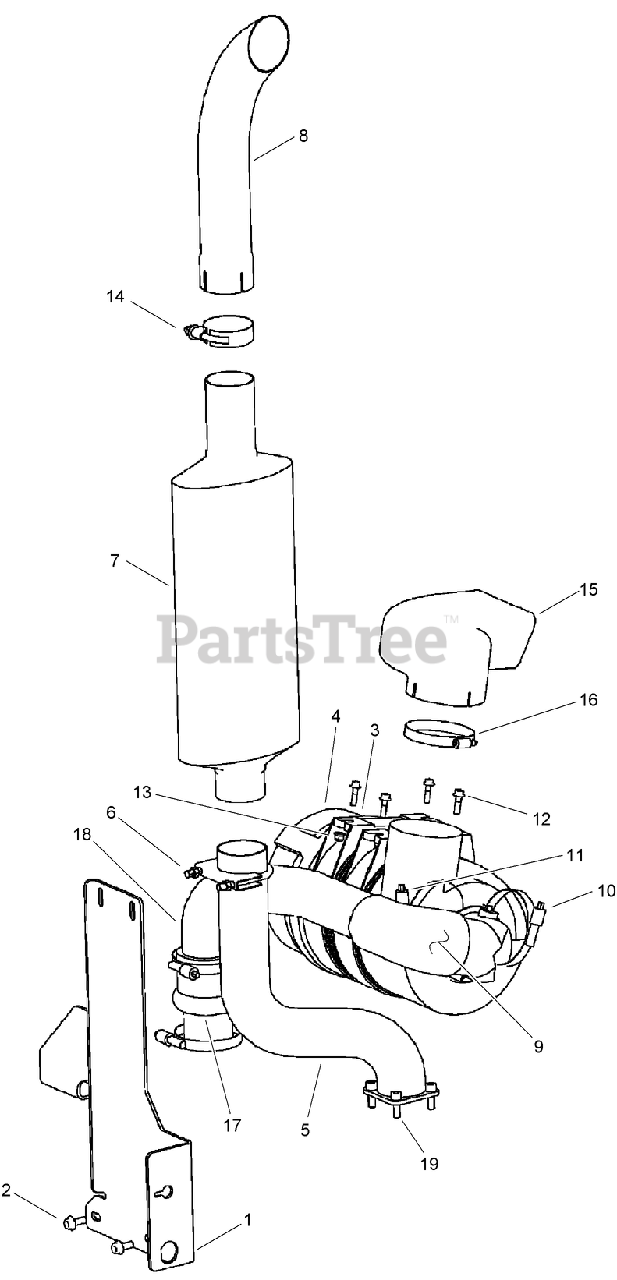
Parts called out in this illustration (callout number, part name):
1	SUPPORT-Muffler Mount
2	SCREW-FLANGE
3	MOUNT-Air Cleaner
4	ASM-Air Cleaner
5	TUBE-EXHAUST
6	BOLT-U, CLAMP
7	MUFFLER-VERTICAL, OVAL
8	EXHAUST-STACK
9	CONNECTOR-AIR INTAKE
10	CLAMP-TORQUE, CONSTANT
11	CLAMP-TORQUE, CONSTANT
12	SCREW, METRIC FLANGE FULL - M8 x 25
13	NUT-TORQUE, PREVAILING
14	CLAMP-MUFFLER
15	INTAKE-Air
16	CLAMP-HOSE, WORM GEAR (HEAVY DUTY)
17	CONNECTOR-Air Intake
18	TUBE-Air Intake
19	SCREW-Soc Hd, M10 x 30 Class 8.8 ZND
